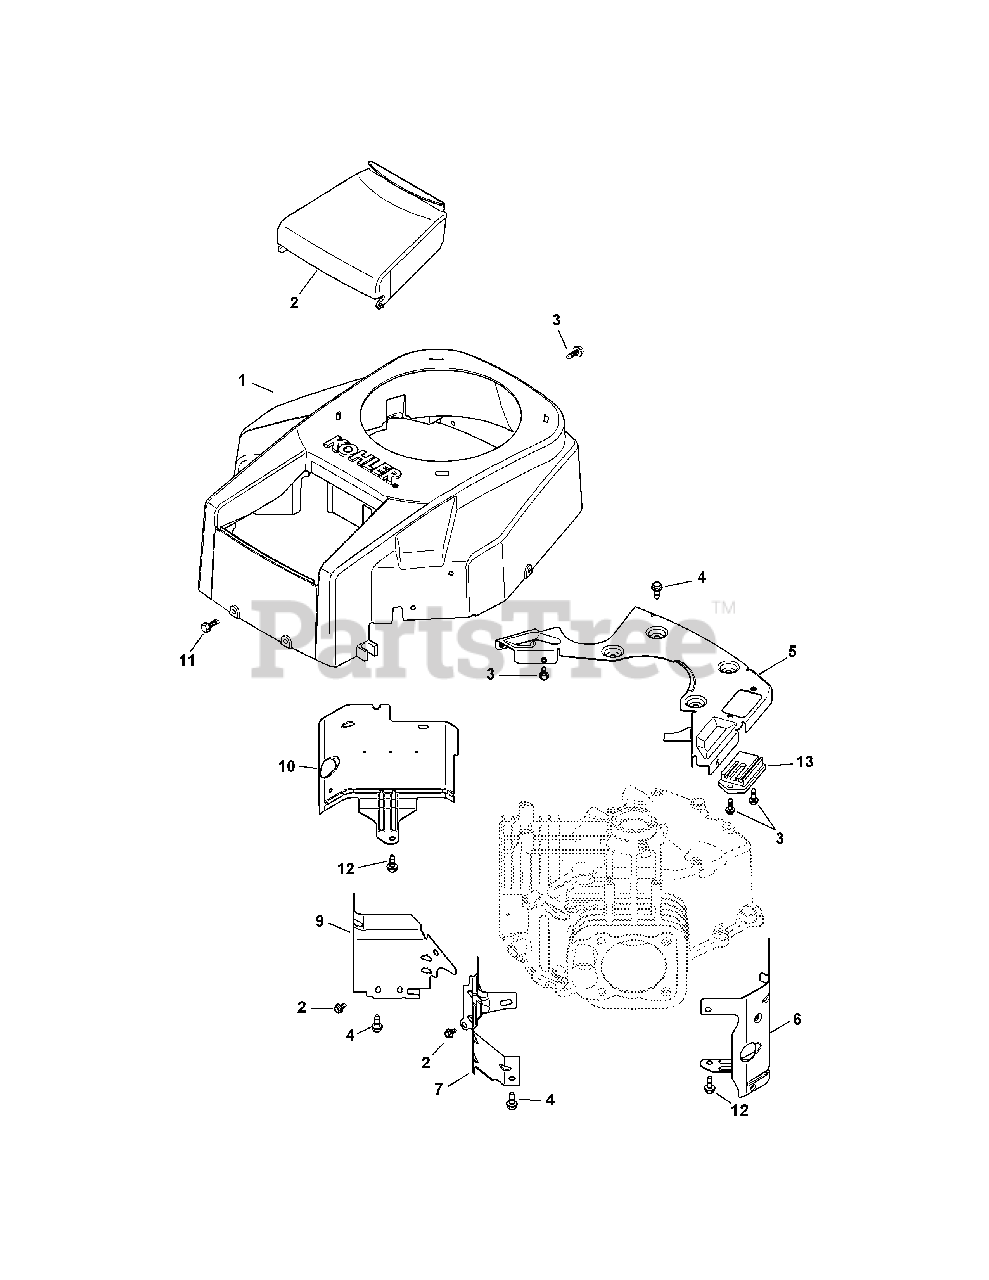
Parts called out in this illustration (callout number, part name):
1	Blower Housing Kit
2	Air Cleaner Cover
3	Flange Screw, M5 x .8 x 16
4	Flange Screw, M6 x 1.0 x 16
5	Backing Plate Kit
6	Cylinder Barrel Baffle, #2 Side
7	Valley Baffle, #2 Cylinder
9	Valley Baffle, #1 Cylinder
10	Cylinder Barrel Baffle, #1 Side
11	Screw, M6 x 1.7 x 18
12	Flange Screw, M6 x 1.0 x 10
13	Regulator/Rectifier
